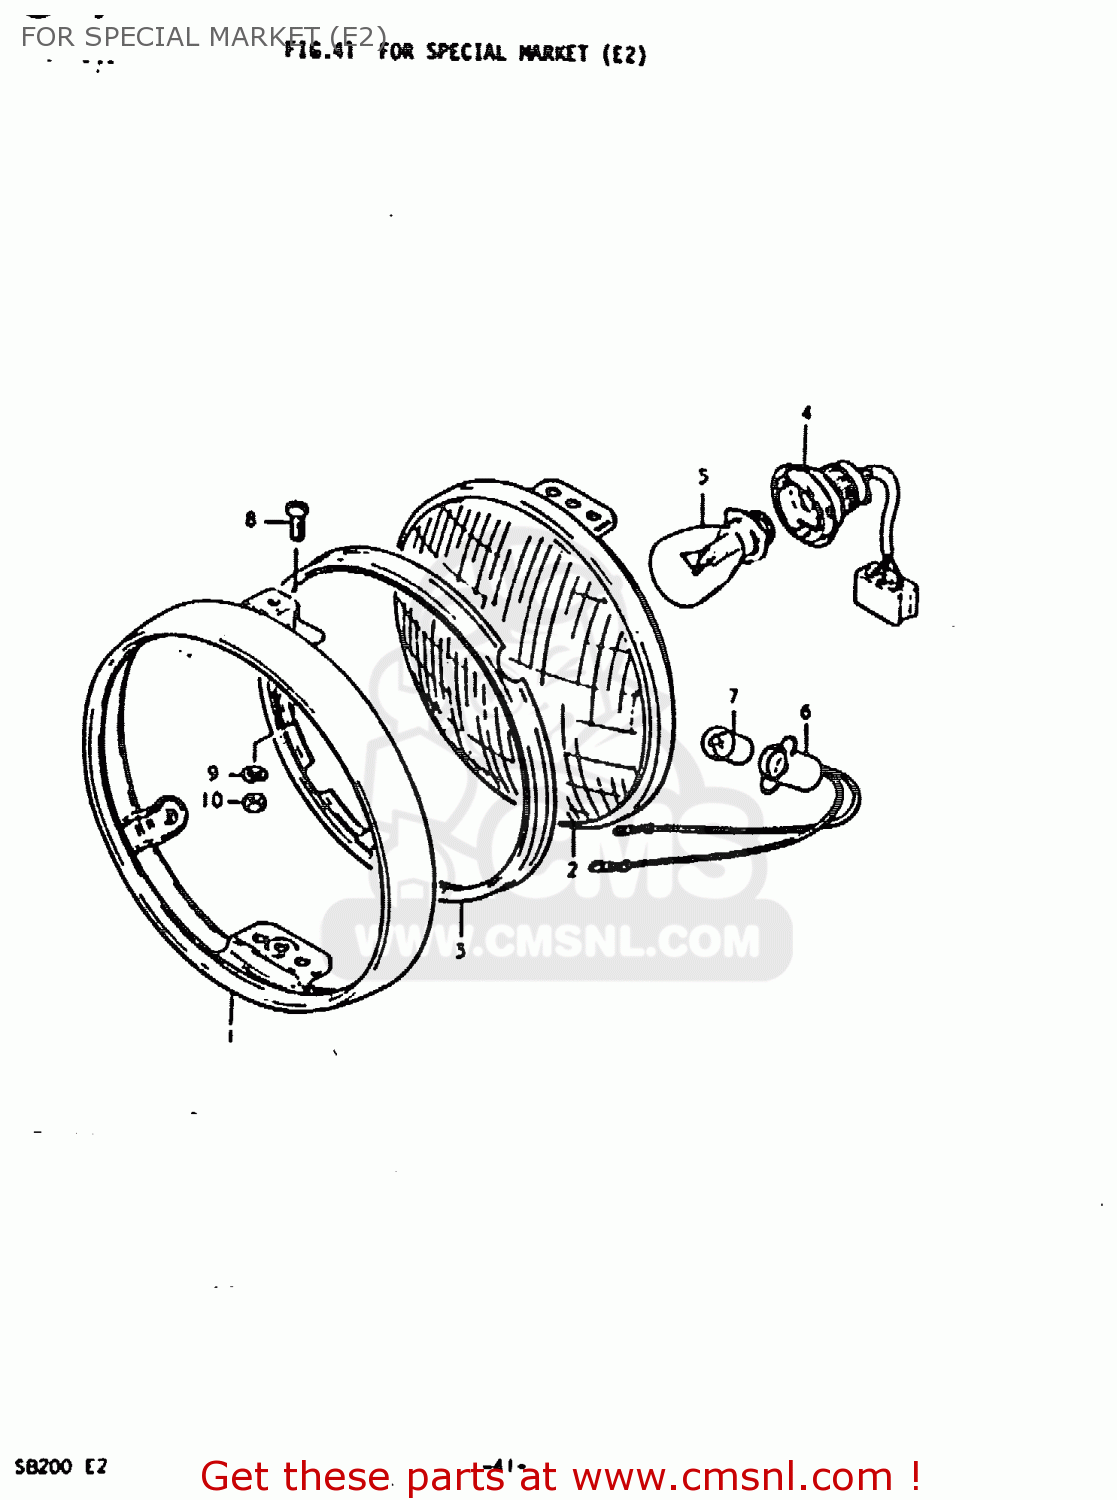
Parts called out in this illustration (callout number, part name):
1	RIM
2	UNIT, HEAD LIGHT
3	RETAINER,HEADLAMP
4	SOCKET
5	BULB 12V35/35W
6	SOCKET
7	BULB(12V3.4W,STANLEY,A72A)
8	SCREW
9	LOCK WASHER
10	NUT
